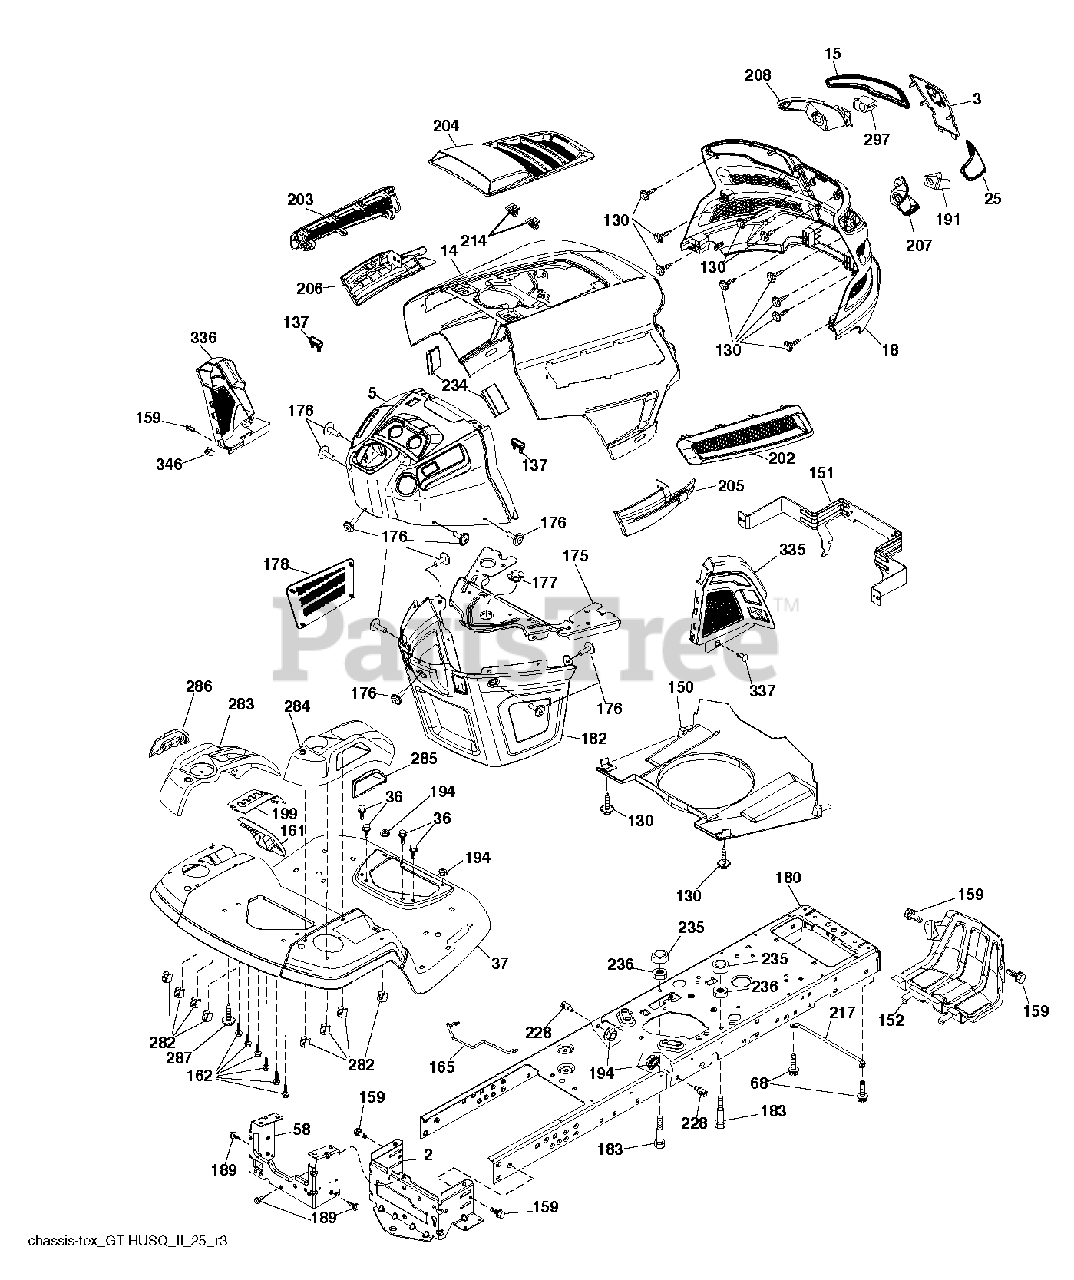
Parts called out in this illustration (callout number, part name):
2	DRAWBAR.LOWER.2PC.18/22
3	APPLIQUE.SUBASM.GT.HUSQ.II
5	DASH.UPP.GT2.DUAL.RD.PTO.MCHOK
14	HOOD.ASM.HUSQVARNA.GT.TEX.ORAN
15	LENS.HEADLIGHT.LH.GTII.2011
18	GRILLE.SUBASM.GT.HUSQ.II
25	LENS.HEADLIGHT.RH.GTII.2011
36	SCREW 5/16"
37	FENDER.TLT.FS.W/CPH/FW/RSF.668
58	DRAWBAR UPPER 2PC SMALL FENDER
68	SCREW LT
130	SCREW.#10 X 0.750.BOS
137	BUMPER DASH
150	AIR.DUCT.GTV.BLACK
151	BRACKET.PIVOT.HOOD.GT.HUSQ.II
152	SHIELD.BROWNING.PNT.GT.V2
159	SCREW, 3/8-16X3/4
161	WINDOW.FUEL.LT.HUSQ.TEX.498
162	SCREW.HI-LO.CONSOLE
165	SUPPORT.TANK.REAR.B/TE
175	PLATE.CROSSMEMBER.HUSQ
176	SCREW.#10-24X5/8.RN.QU
177	BUSHING, STEERING
178	CARGO.ASM.NET.TXGT.W/C
180	CHASSIS.STAMPING.LT/GT
182	DASH.LOWER.COMMON.12V.ADAPTOR
183	BOLT.5/16-18X1-1/4 FULL THD
189	SCREW
191	INSERT.REFLECTIVE.RH.HUSQ.GTII
194	NUT LOCK HEX FLANGE 5/16-18
199	PLATE.DECK.LIFT.HUSQ.LT
202	VENT.SIDE.RH.GT.HUSQ.II.
203	VENT.SIDE.LH.GT.HUSQ.II.498
204	VENT.TOP.HUSQ.GT2
205	SIDE.TRIM.RH.GT.HUSQ.II
206	SIDE.TRIM.LH.GT.HUSQ.II.GRAY
207	BEZEL LIGHT.RH.GT.II.MYLAR
208	BEZEL LIGHT.LH.GT.II.MYLAR
214	CLIP.RETAINER.TINNER.
217	ROD.PIVOT.HOOD
228	STUD.FASTNER.W/ANTI-ROTATE
234	BUMPER.HOOD.TEX.HUSQVARNA
235	SPACER FENDER
236	NUT.CENTERLOCK.5/16-
282	CLIP.RETAINER.CONSOLE.LT.HUSQ
283	CONSOLE.DECK.LIFT.R.SDFL.HUSQ
284	CONCOLE.CNTRL.PDL.HUSQ.LT.498
285	CONSOLE INSERT RH
286	CONSOLE.INSRT.LH.HUSQ.LT.BLACK
287	SCREW 1/4X20
297	INSERT.REFLECTIVE.LH.HUSQ.GTII
335	COVER.RH.CLOSE.OUT.BLACK
336	COVER-LH.LOWER.DASH.GT2.BLACK
337	SCREW, 3/8-16X3/4
346	CLIP,INSULATOR
